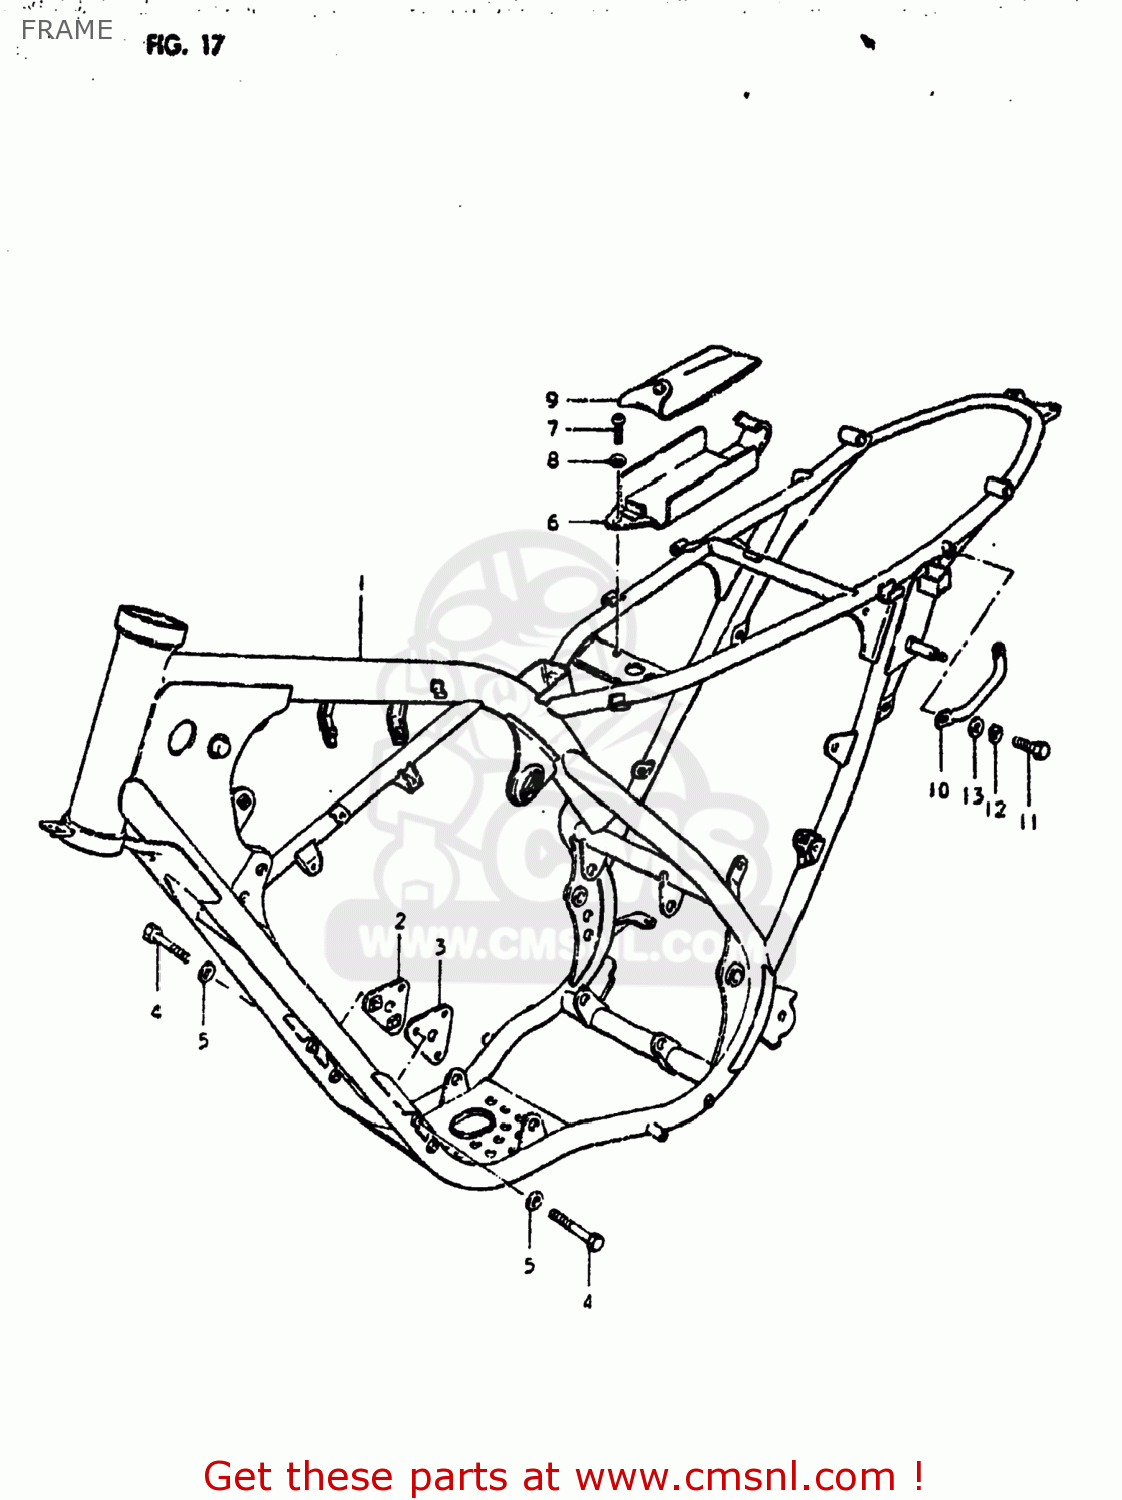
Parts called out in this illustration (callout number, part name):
1	FRAME
2	PLATE,ENGINE MOUNTING
3	PLATE,ENG MTG,L
4	BOLT 8X55
5	WASHER
6	HOLDER,TOOL
7	SCREW
8	WASHER
9	TOOL ASSY
10	GRIP,FRAME HANDLE
11	BOLT
12	LOCK WASHER
13	WASHER
